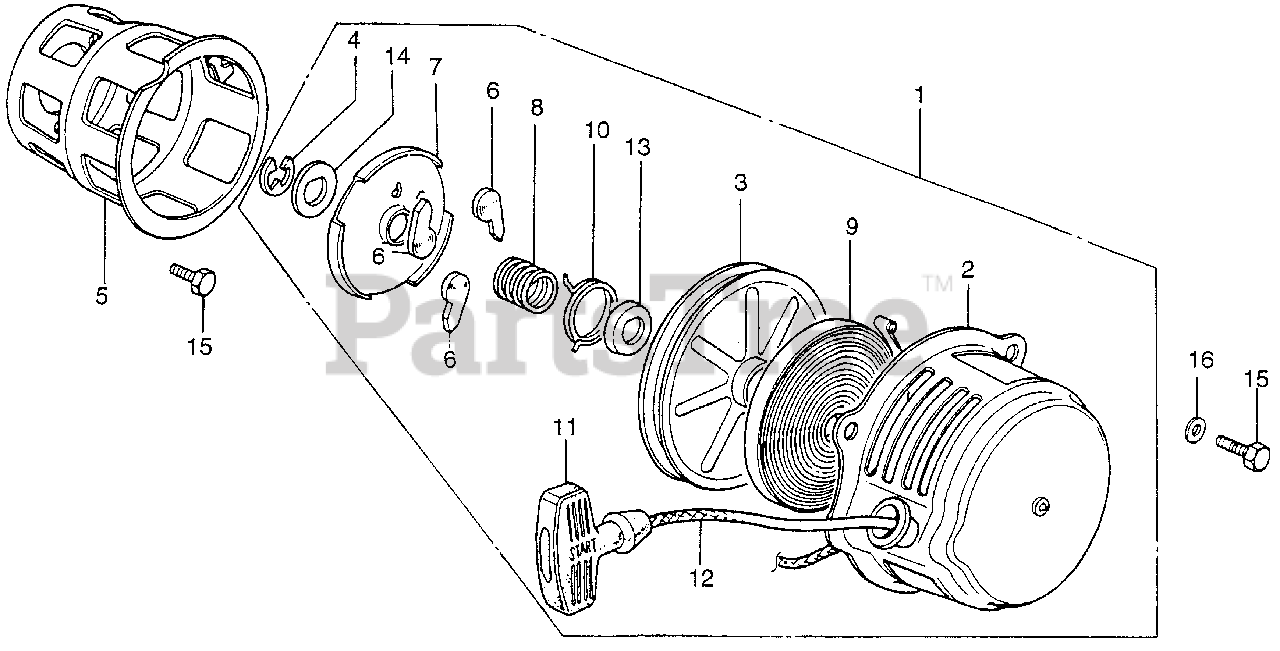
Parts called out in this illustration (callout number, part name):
1	STARTER ASSY., RECOIL *R8* (BRIGHT RED) (N/A: SEE COMPONENTS)
2	CASE, RECOIL STARTER *R8* (BRIGHT RED)
3	PULLEY, RECOIL STARTER (NOT AVAILABLE)
5	PULLEY, STARTER (NOT AVAILABLE)
6	RATCHET, STARTER
7	PLATE, FRICTION
8	SPRING, FRICTION
9	SPRING, STARTER RETURN
10	SPRING SET
11	KNOB SET, STARTER
12	ROPE, STARTER (#6X64")
15	BOLT, HEX. (6X12)
16	WASHER, PLAIN (6MM)
